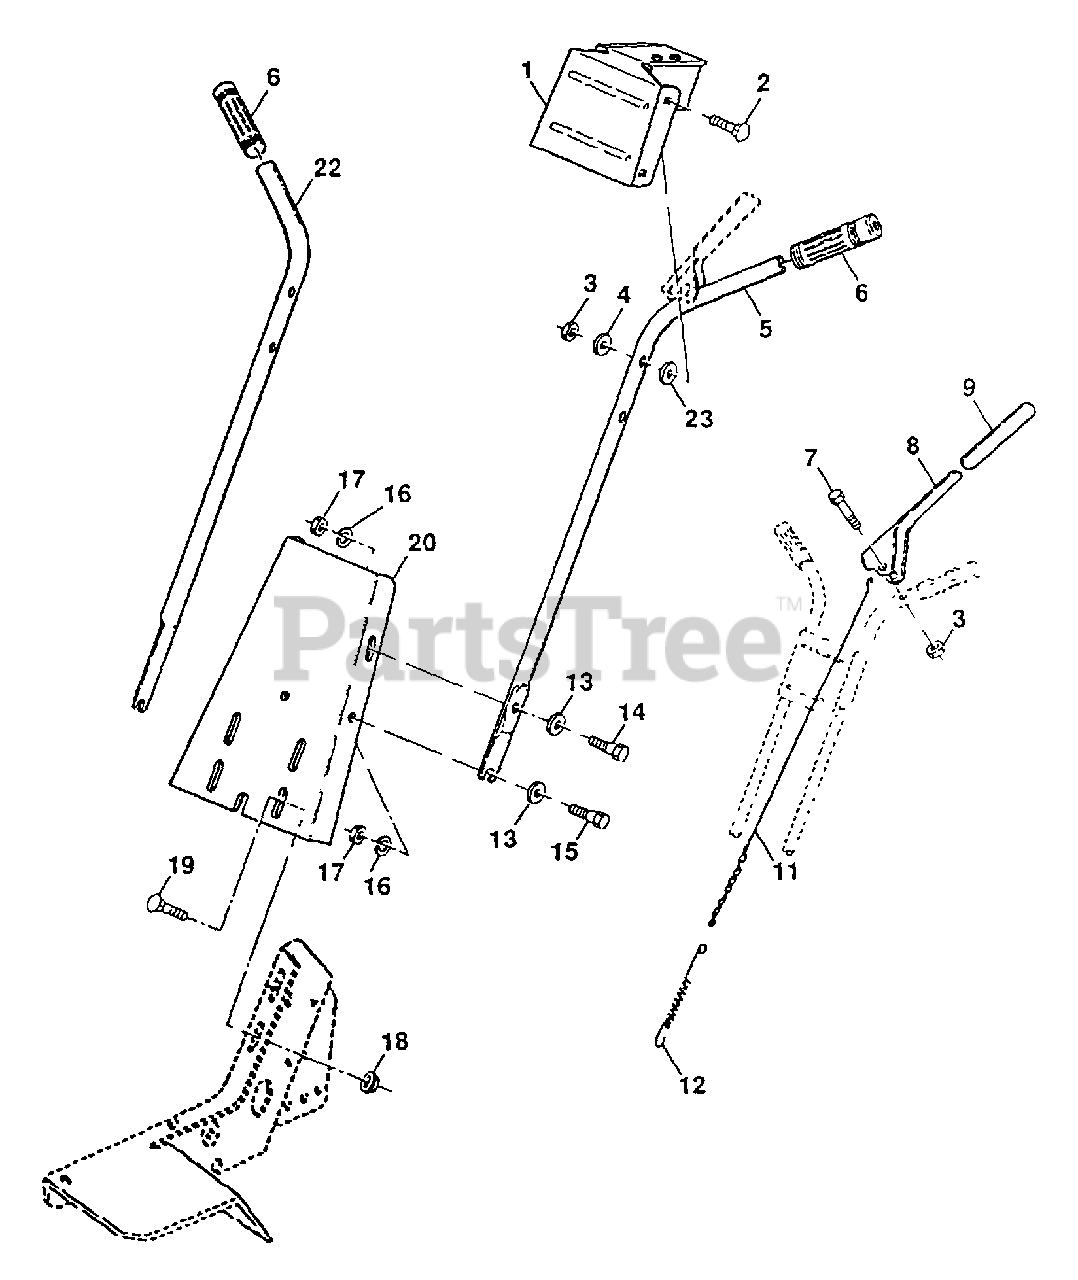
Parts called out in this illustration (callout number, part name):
1	Bracket, Handle
2	Bolt, Carriage 5/16-18 UNC x 1-1/2
3	Locknut, Crown 5/16-18
4	Washer 11/32 x 11/16 x 16 Ga.
5	Handle, L.H.
6	Grip, Handle
7	Bolt, Hex 5/16-18 x 1-1/2
8	Lever, Control, Tine
9	Grip, Lever
11	Cable, Control, Tine
12	Spring, Extension
13	Washer 3/8 x 7/8 x 14 Ga.
14	Bolt, Hex Hd 5/16-18 x 1 (AYP part number)
15	Bolt, Hex Hd 5/16-18 x 3/4
16	Washer, Lock 5/16
17	Nut, Hex 5/16-18
18	Nut, Flanged 5/16-18 (AYP part number)
19	Bolt, Carriage 5/16-18 x 3/4 Gr. 5
20	Panel, Handle
22	Handle, R.H.
23	Washer 13/32 x 13/16 x 12 Ga
